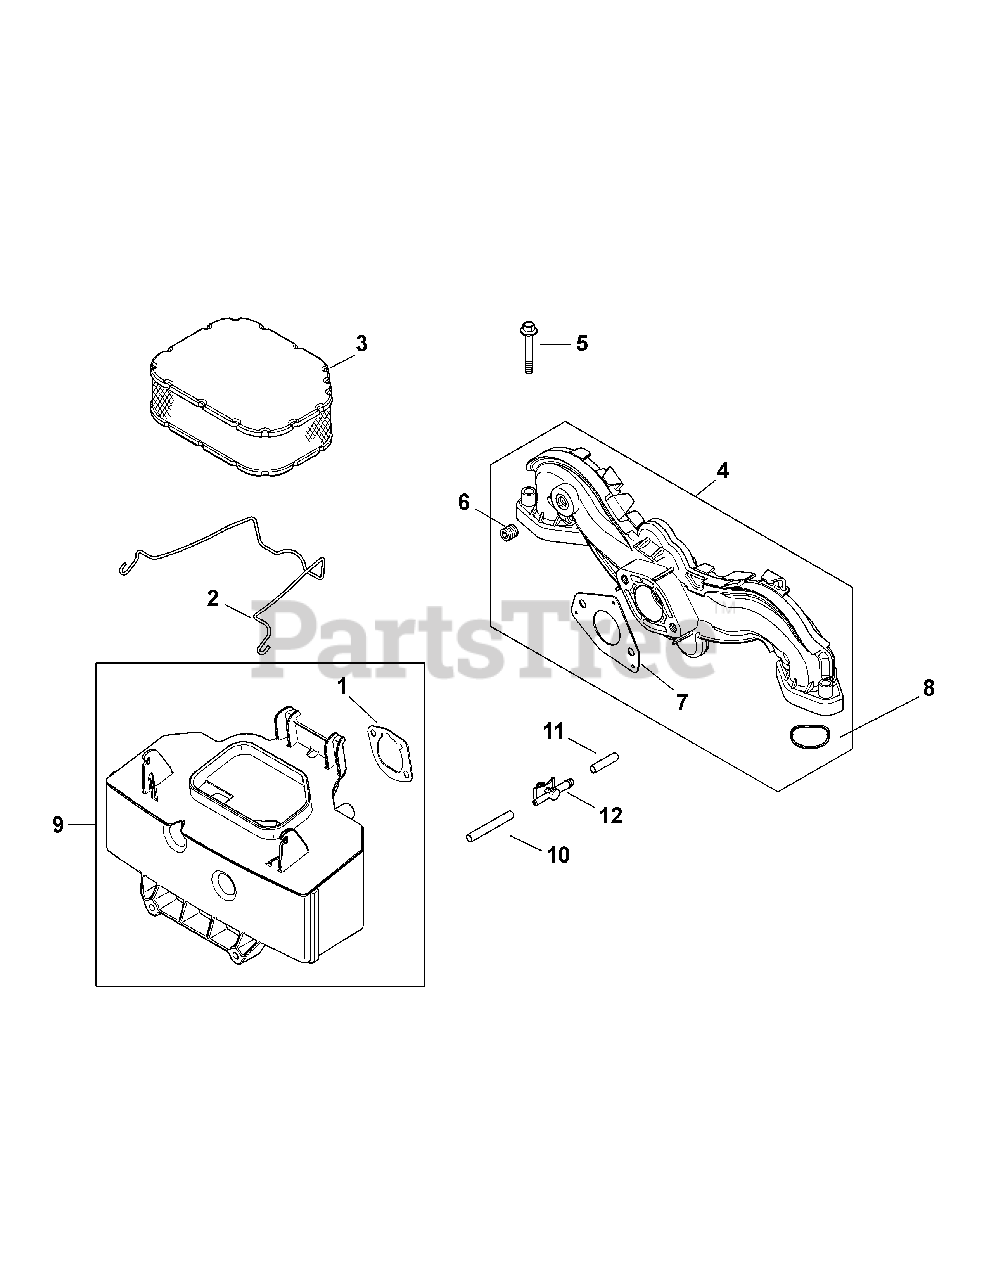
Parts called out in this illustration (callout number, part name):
1	Air Cleaner Base Gasket
2	Air Cleaner Element Latch
3	Air Filter Element
4	Intake Manifold Kit
5	Screw, M6 x 1.0 x 40
6	Pipe Plug, 1/8
7	Carburetor Gasket
8	O-Ring, Intake Port
9	Air Cleaner Base
10	Evaporative Hose, 20"
12	Evaporative Connector
